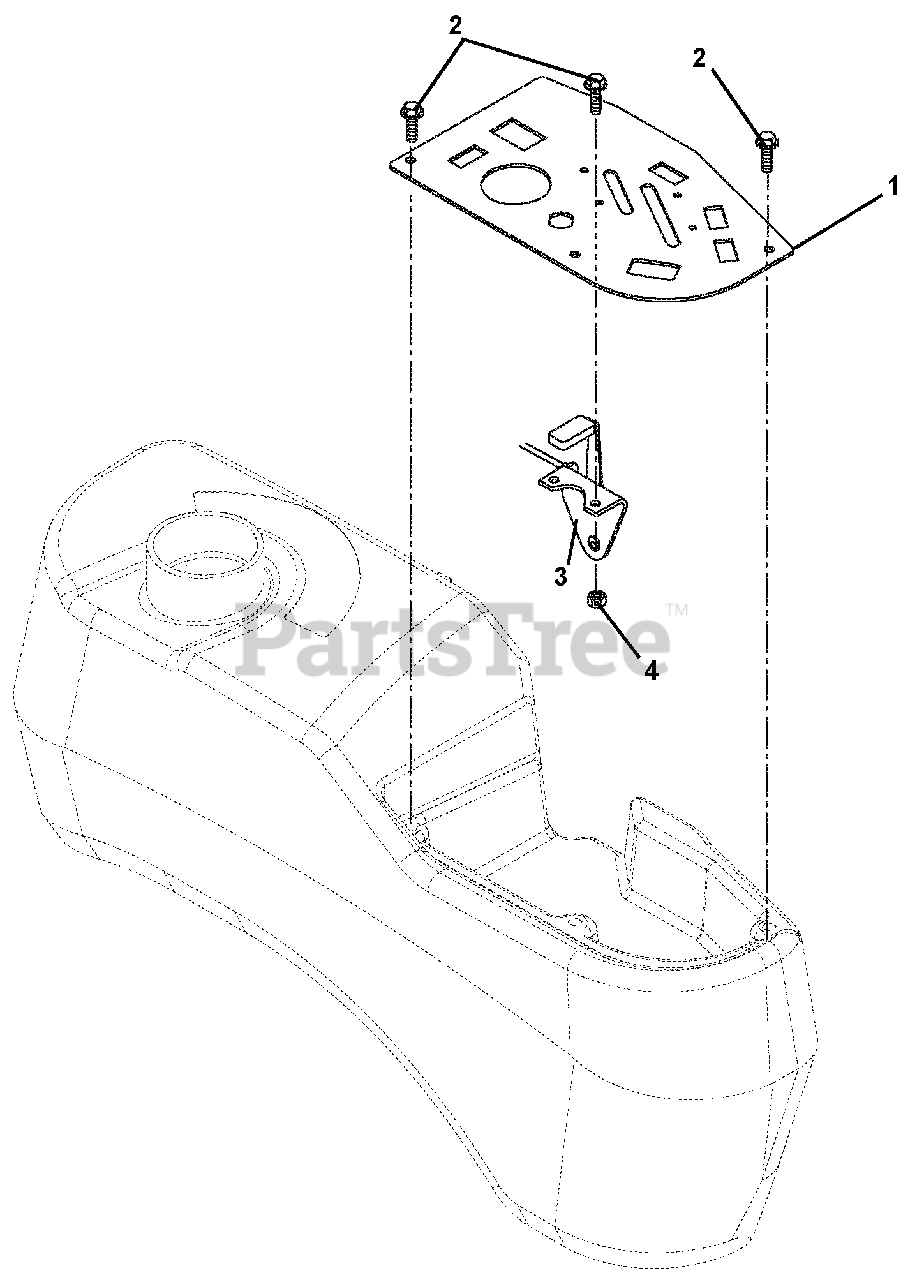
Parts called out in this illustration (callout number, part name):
1	Panel-Control
2	Screw-Machine 10-24 x .50 Hex Washer Head
3	Throttle, Control
4	Nut-Locking-Nylon 10-24 With Insert
